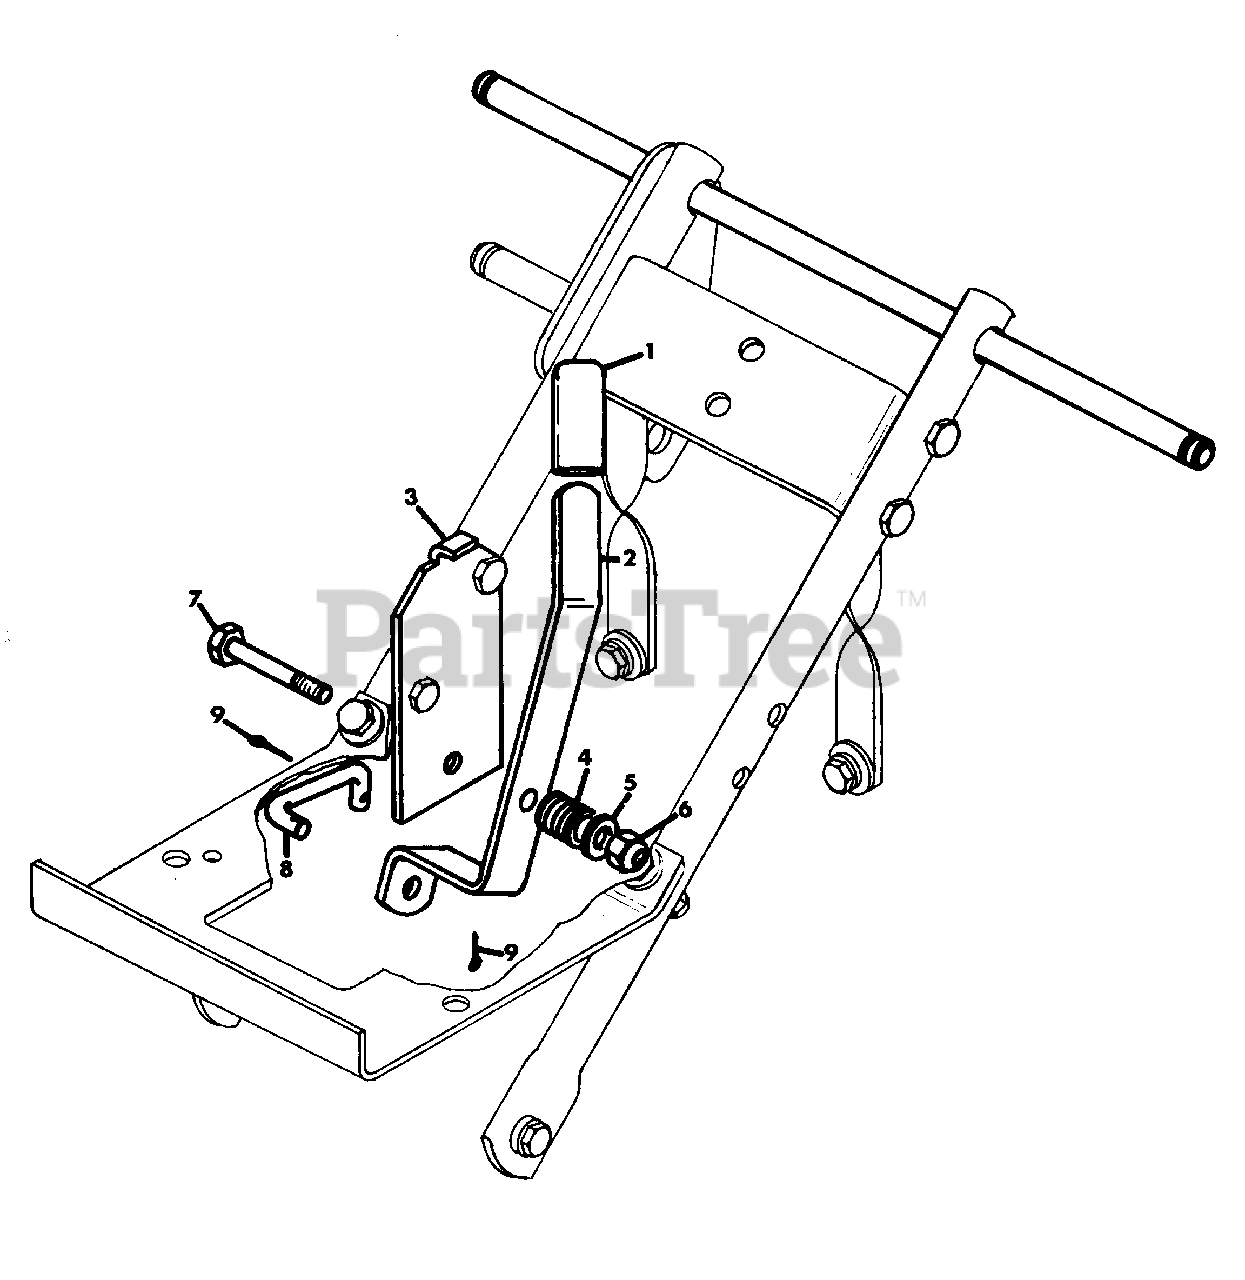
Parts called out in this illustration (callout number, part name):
1	GRIP, HANDLE
2	LEVER, HI-LO
3	BRACKET, HI-LO
4	SPRING, COMP. 1X.78
5	WASHER, FLAT .406X.812X.065
6	NUT, LOCK 3/8-16
7	BOLT, HEX 3/8-16X1.75
8	ROD, HI-LO
9	PIN, COTTER .09X1.00
